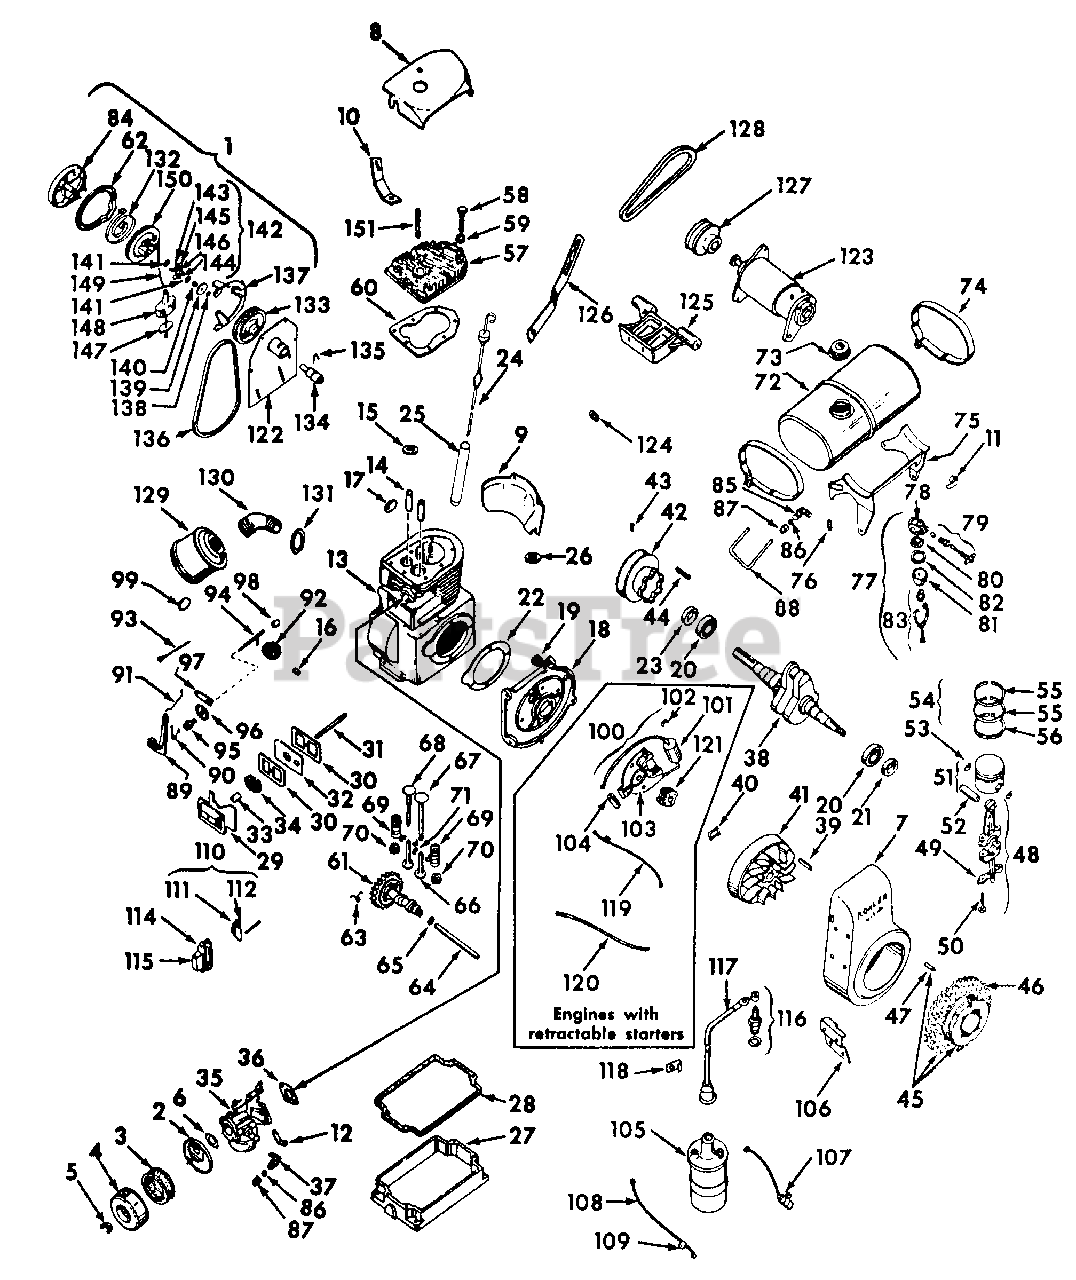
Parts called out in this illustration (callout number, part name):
1	Starter Assy, Retractable
2	Base, Air Cleaner
3	Element, Air Cleaner Filter
4	Cover, Air Cleaner
5	Nut, Air Cleaner Wing
6	Gasket, Air Cleaner
7	Housing Assy, Blower
8	Baffle, Cylinder Head Air
9	Baffle, Cylinder Air
10	Brace, Retractable Starter
11	Clip, Choke Cable
12	Bracket, Choke
13	Crankcase Assy
14	Guide, Valve
15	Insert, Exhaust Valve
16	Shaft, Governor
17	Plug, 1-1/8 Expansion
18	Plate, Crankcase Brg
19	Plug, 5/8 Button, Crankcase Brg Plate
20	Bearing, Crankcase Ball
21	Seal, Crankcase Brg Plate Oil
22	Gasket, Brg Plate
23	Seal, Crankcase Oil
25	Tube, Oil Fill
26	Insert, Intake Valve
27	Base, Oil Pan
28	Gasket, Oil Pan Base
29	Cover w/Filter, Breather
30	Gasket, Breather
31	Stud, Breather Cover
32	Plate Assy, Breather
33	Seal, Breather
34	Filter, Breather
35	Carburetor Assy
36	Gasket, Carburetor
37	Elbow, Carburetor to Fuel Line
38	Crankshaft
39	Key, Crankshaft
40	Washer, Flywheel Tension
42	Pulley w/Clutch Drive Plate, Flywheel
43	Screw, Flywheel Pulley Set
44	Key, 1/4 X 7/8 Sq Parallel
45	Cup Assy, Flywheel Drive
46	Screen, Drive Cup Grass
47	Pin, Flywheel Drive Cup
48	Rod Assy, Connecting, Std
49	Lock, Connecting Rod Screw
50	Screw, Connecting Rod
51	Piston Assy, Std
52	Pin, Piston, Std
53	Retainer, Piston Pin
54	Ring Set, Piston, Std
55	Ring, Compression
56	Ring, Oil Control
57	Head, Cylinder
58	Screw, Cylinder Head
59	Washer, Cylinder Head
60	Gasket, Cylinder Head
61	Camshaft Assy
62	Flange, Intermediate
63	Spring, Camshaft Actuating
64	Pin, Camshaft
65	Shim, Camshaft, .005
66	Tappet, Valve
67	Valve, Intake
68	Valve, Exhaust
69	Spring, Valve
70	Retainer, Valve Spring
71	Key, Valve Spring Retainer
72	Tank Assy, Fuel w/Filler Cap
73	Cap, Fuel Filler
74	Strap, Fuel Tank
75	Bracket Assy, Fuel Tank
76	Nipple, 1/8 X 3/4 C-Z Pipe
77	Filter Assy, Fuel
78	Body, Fuel Filter
79	Valve Assy, Needle
80	Screen, Filter
81	Bowl, Fuel Filter Glass
82	Gasket, Fuel Filter Bowl
83	Bail Assy, Fuel Filter Bowl
84	Cover, Retractable Starter
85	Connector, Fuel Tank
86	Sleeve, Fuel Line
87	Nut, Fuel Line
88	Line, Fuel Filter to Carburetor Fuel
89	Lever, Governor
90	Spring, Governor
91	Linkage, Governor
92	Gear Assy, Governor
93	Pin, Governor Stop
94	Shaft Assy, Governor Cross
95	Bushing, Cross Shaft
96	Disc, Governor Regulating
97	Bracket, Speed Control
98	Bearing, Cross Shaft Needle
99	Plug, 1-1/8 Expansion
100	Magneto Assy
101	Coil, Magneto
102	Clamp, Magneto Coil
103	Stator, Magneto
104	Condenser, Magneto
105	Coil, Ignition
106	Bracket, Coil Mounting
107	Condenser, Ignition Coil
108	Cable Assy, Condenser to Breaker
109	Clip, Condenser to Breaker Cable
110	Bracket & Breaker Assy
111	Breaker Point Set
112	Bracket, Point Breaker
114	Cover, Breaker
115	Gasket, Breaker Cover
116	Plug, Spark (Champion)
117	Kit, Hi-Tension Spark Plug Cable Lead
118	Clip, Spark Plug Cable
119	Cable Assy, Ground
120	Sleeve, Ground Cable
121	Magnet, Magneto
122	Bracket, Retractable Starter
123	Motor Generator
124	Shim, Motor Generator Mounting Bolt
125	Bracket, Motor Generator Mounting
126	Brace, Motor Generator Adjusting
127	Pulley, Motor Generator Drive
128	Belt, Motor Generator Drive
129	Muffler, Exhaust
130	Elbow, Exhaust Muffler
131	Nut, Exhaust Muffler Elbow Lock
132	Spring, Starter Rewind
133	Pulley Assy, Retractable Starter
134	Bearing, Retractable Starter Ball
135	Retainer, Retractable Starter Ball Brg
136	Belt, Retractable Starter
137	Flange, Mounting
138	Ring, Retaining
139	Washer, Brake Retainer
140	Spring, Brake
141	Washer, Brake Fiber
142	Shoe Assy, Friction
143	Plate, Friction Shoe Spring
144	Spring, Friction Shoe
145	Plate, Friction Shoe
146	Lever, Friction Shoe Brake
147	Insert, Handle
148	Handle, Starter Cord
149	Cord, Starter
150	Rotor, Starter
151	Stud, Cylinder Head
